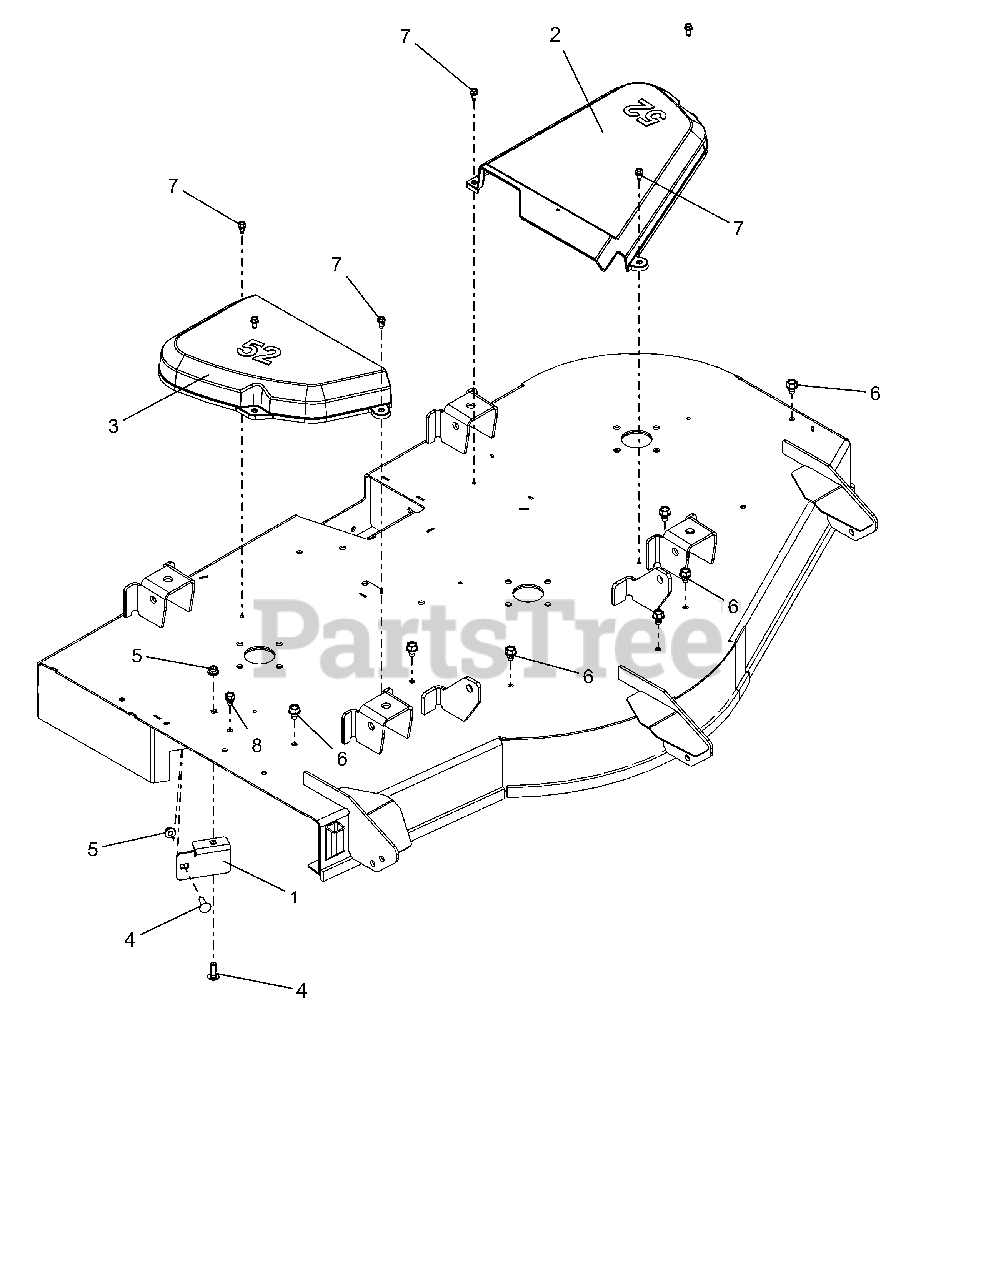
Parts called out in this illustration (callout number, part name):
1	STRIP, DEFLECTOR - 52"
2	COVER, BELT 52" LH
3	COVER, BELT 52" RIGHT
4	BLT,RHSN .31-18X1.00 G5 ZCC
5	NUT,NYL-FLG .31-18 GF ZCC
6	SCR,TAP .375-16X.50 HWH TR ZCC
7	SCR-TAP .25-20X.50 HWH ZCC
8	SCR,TAP .312-18X.50 HWH TR ZCC
